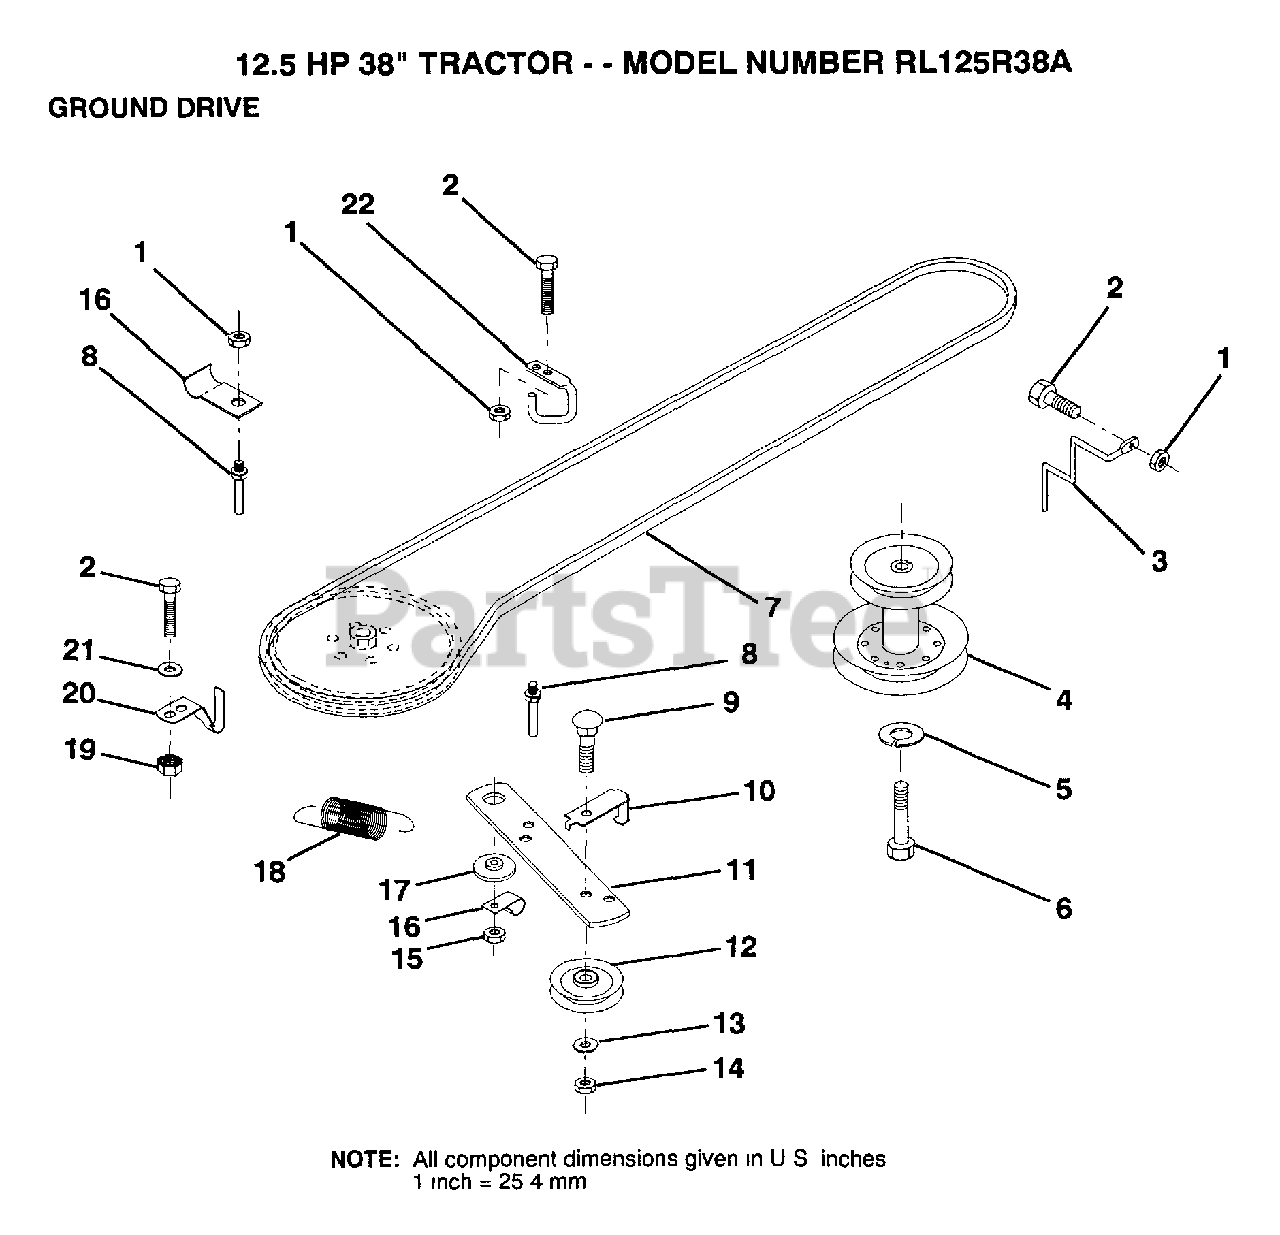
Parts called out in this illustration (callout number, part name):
2	BOLT
3	KEEPER MWR DR BLT
5	LOCKWASHER
6	BOLT
7	BELT
8	"KEEPER,DRIVE BELT"
9	BOLT
10	"KEEP,IDLER DR BEL"
13	WASHER
14	LOCKNUT
16	"CLIP,INSULATOR"
17	SPACER RETAINER
20	"KEEPER,DR BELT "
21	WASHER
22	"KEEPER,FRA DR BEL"
